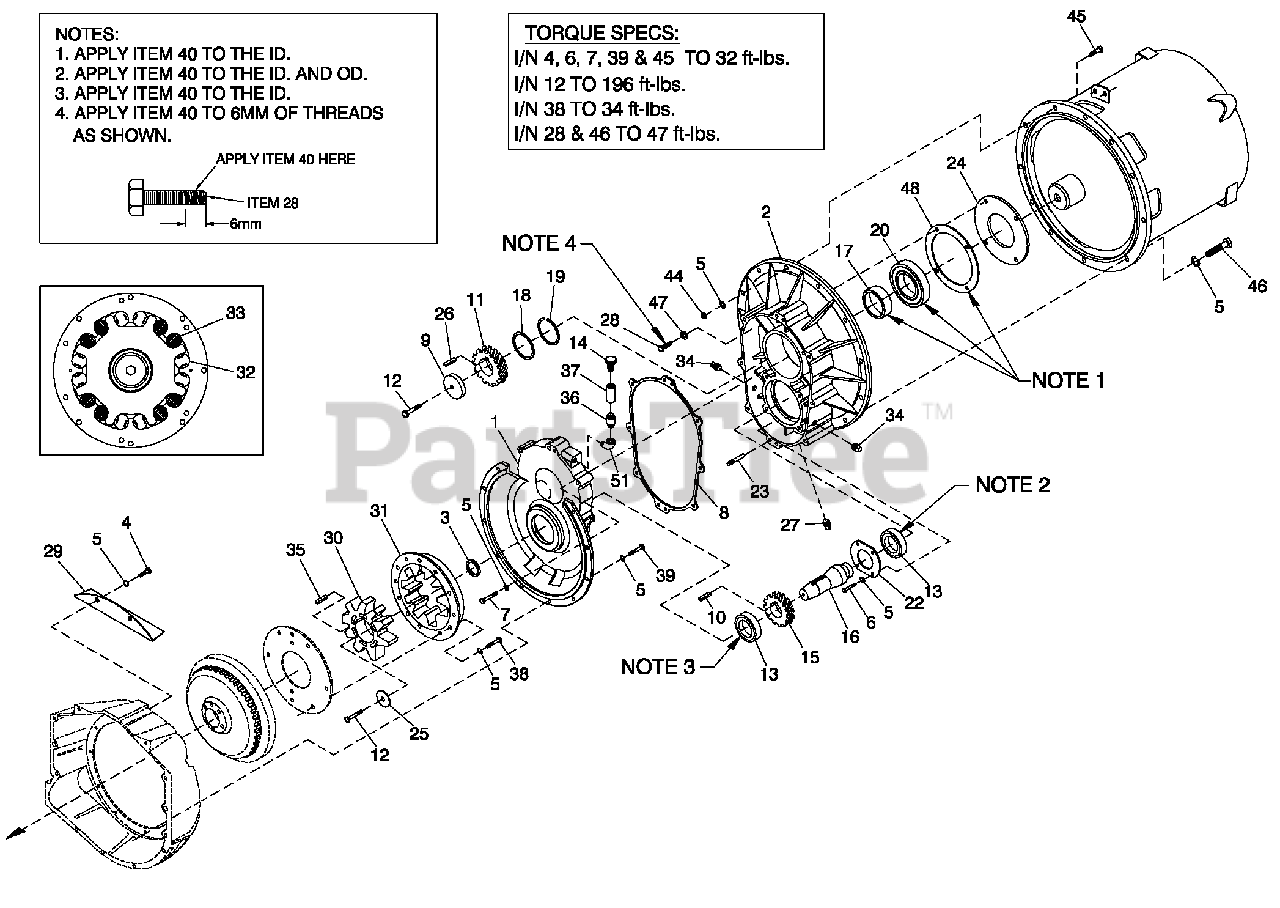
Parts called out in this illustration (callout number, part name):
1	GEAR CASE ENG. MACHINED
2	GEAR CASE ALT. MACHINED
3	SEALOIL
4	S CREW HHC M10l1.5X 20 G8.8
5	WASHER LOCK M10
6	S CREW HHC M10l1.5X 25 G8.8
7	S CREW HHC M10l1.5X 70 G8.8
8	GASKET 390 GEAR BOX
9	S PACER .69 X 2.75 X .37 ST/ZNC
10	KEY 10X16X46
11	GEAR OUTPUT 1.65:1
12	SCREW HHC M16-2.0X 35 G10.9
13	BALLBRG65X 120X23
14	BREATHER
15	GEAR INPUT 1.65:1
16	GEAR INPUT 2:1 50HZ390
17	SHAFT 390 INPUT GEAR
18	COLLAR HARDENED
19	SEALOIL
20	SNAP RING INT 120MM
22	BEARING #6213 SEALED
23	PLATE INTRNLBRG RET
24	PIN DOWEL M8X 24
25	PLATE BEARING THRST
26	SPACER STRESSPROOF
27	KEY 10X16X40
28	PLUG PIPE 3/8"MAGNETIC
29	SCREW HHFC M10-1.5X 25 G10.9
30	COVER GEARBOX GUARD
31	COUPLING INNER DRAWN
32	COUPLING OUTER MACHN
33	DAMPER GB CPLRVIBRA
34	DAMPER GB CPLRVIBRA
35	PLUG STD PIPE 3/8 STEEL SQ HD
36	KEY 10X16X50
37	NIPPLE PIPE3/8NPTX 3-1/2
38	COUPLING FULL 3/8-18
39	SCREW HHC M10l1 .5X 25 G8.8
40	RETAINING COMPOUND
44	NUT HEX M10-1.5G8 YELCHR
45	SCREW HHC M10l1 .5X 60 G8.8
46	SCREW HHC M10l1 .5X 40 G10.9
47	WAS HER FLAT M10 S EALING COPPER
48	GASKET SEAL PLATE 390 G B
50	THREADLOCK AND SEALANT
51	ELB OW 90DSTREET3/8
